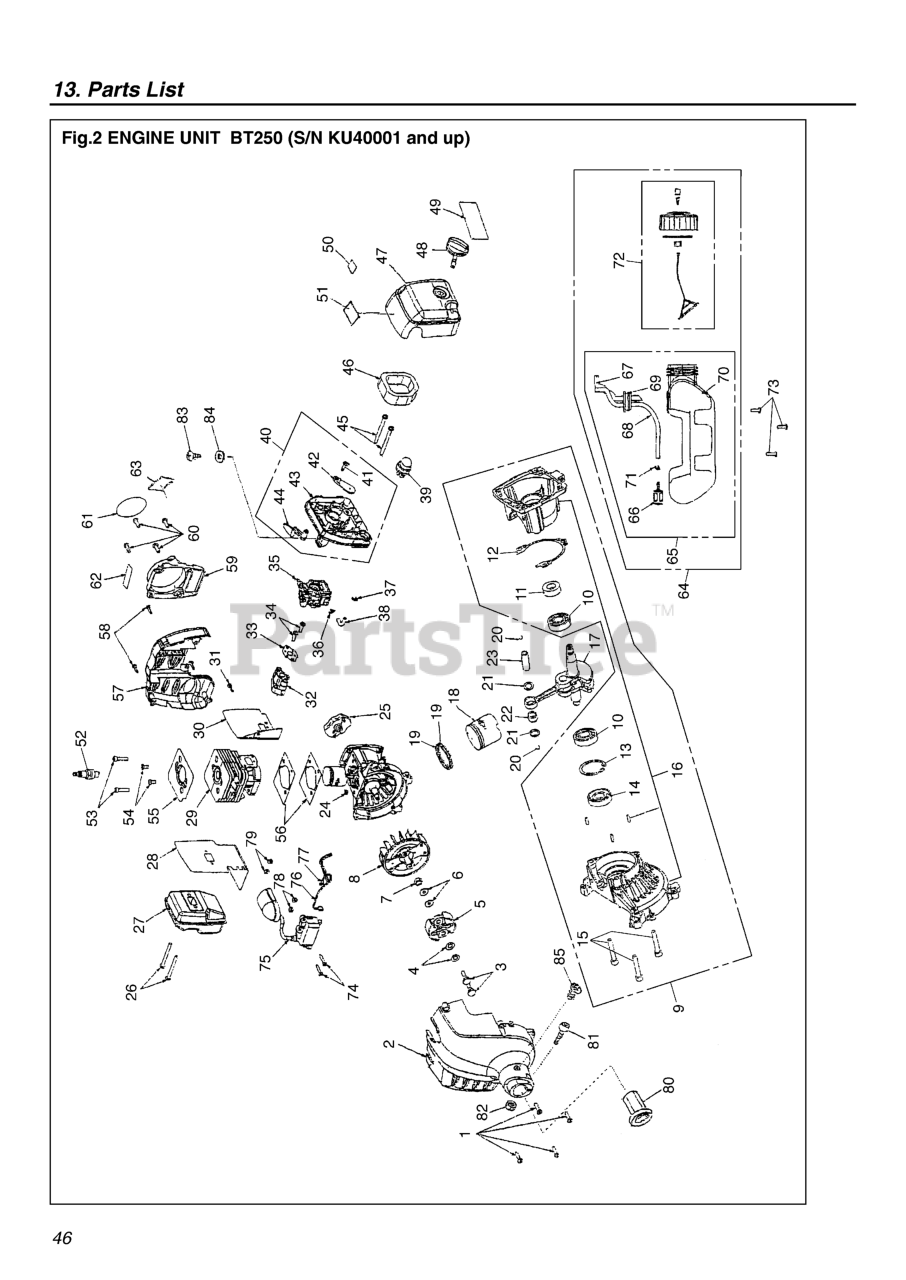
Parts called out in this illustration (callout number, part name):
1	SCREW
2	FRONT HOUSING
3	SCREW, CLUTCH
4	WASHER, CURVED
5	CLUTCH ASSY
6	WASHER, PLAIN
7	NUT
8	ROTOR
9	CRANKCASE & SHAFT ASS
10	BEARING
12	GASKET, CRANKCASE
13	RING
14	SEAL
16	CRANKCASE ASS
17	CRANKSHAFT ASS
18	PISTON
19	RING, PISTON
20	CLIP RING
21	WASHER
22	NEEDLE BEARING
23	WRIST PIN
25	PULLEY ASS
26	BOLT, MUFFLER
27	MUFFLER & ARRESTER
28	MUFFLER GASKET
29	CYLINDER
30	GASKET, INSULATOR
31	SCREW, TORX
32	INSULATOR
33	GASKET, CARBURETOR
34	SCREW, TORX
35	CARBURETOR
36	CLIP, HOSE
37	CLIP, HOSE
38	PLASTIC RUBBER, TUBING
39	PRIMER ASS
40	CHOKE LEVER & PLATE ASS
41	SCREW, TORX
42	CHOKE PLATE
43	CARBURETOR PLATE
44	CHOKE LEVER
45	BOLT, CARBURETOR
46	ELEMENT
47	COVER ASS
48	KNOB
50	LABEL, START
51	LABEL, CAUTION
52	SPARK PLUG
53	CAP SCREW
54	SCREW, TORX
55	PLATE FIN
56	GASKET, CYLINDER
57	REAR HOUSING
58	SCREW, TORX
59	RECOIL ASSY
60	SCREW, TORX
61	LABEL, STARTER
62	LABEL, E START
63	LABEL, EMISSION
64	TANK & CAP ASS
65	TANK ASS
66	FILTER
67	PIPE RETURN
68	PIPE FUEL
69	TANK GROMMET
70	TANK
71	CLIP, HOSE
72	CAP ASS
73	BOLT, TORX
74	BOLT, TORX
75	COIL & BOLT ASS
76	LEAD ASS
77	LEAD ASS
78	SPACER
80	CUSHION
81	BOLT, M6 x 30
83	SCREW
84	WASHER
85	SCREW
